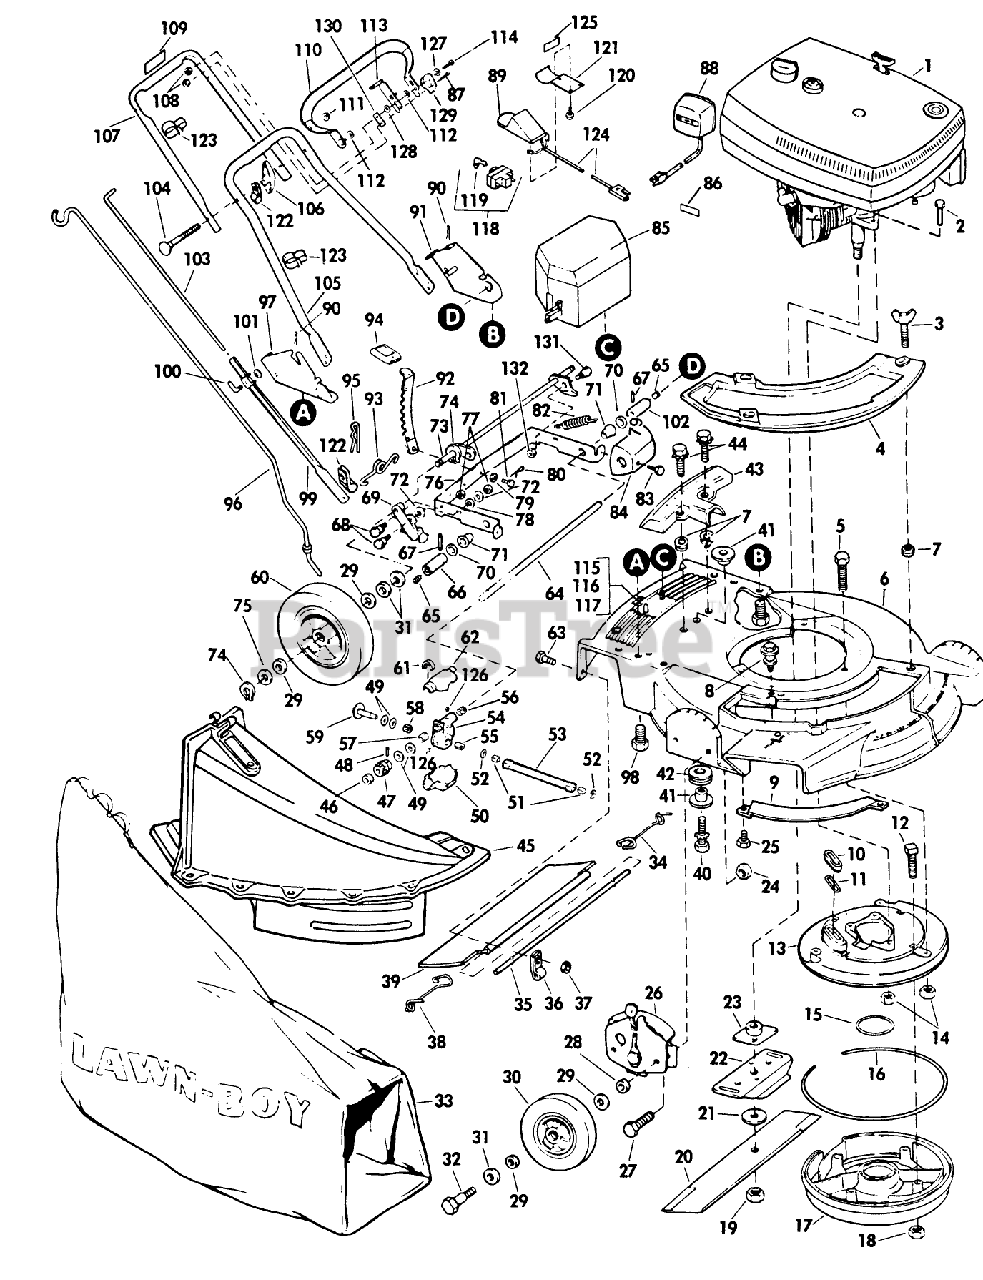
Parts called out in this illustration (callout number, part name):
1	See Note #2 at bottom of this page.
2	BOLT F
3	WING SCREW LAWRE
5	SCREW V
9	BAR-TOE
10	SLEEVE
11	GASKET S
12	SCREW
14	NUT-LOCK F
16	Gasket Muffler (outside)
18	LOCKNUT E
19	NUT-BLADE
21	WASHER
23	PLATE AND COLLAR ASM
24	NUT-LOCK F
28	WASHER WROUGHT
29	WASHER
30	WHEEL & TIRE KIT
31	SPACER
32	BOLT WHEEL
33	ORD LB 89802 WHOLE GOODS
34	SPRIG T/SHLD ASOC
35	ROD 21" ADVANCE
36	CLAMP ROD KMC
37	LOCKNUT E
38	SPRING;TRAILING SHIELD RH
41	SPACER ECK PRES
42	GROMMET
43	COVER
44	SCREW SEMS TRM HEX HD
46	WASHER
48	ROLL PIN
49	THRUST WASHER
51	BUSHING
52	O Ring
58	NEEDLE BEARING
62	GEAR COVER UPPER
64	DRIVE SHFT TAG AY
65	Plug
67	PIN
68	BOLT RB&W
72	WASHER S
74	RET RING
75	SPACER
77	STOP NUT
79	WASHER SPRING LAR
81	PIN
82	SPRING
84	GUARD
87	SCREW-HANDLE STOP
90	HAIR PIN
92	LEVER
93	SPRING N.A.S
94	KNOB
96	ROD GRASSBAG
98	SCREW
103	ROD CONTROL
106	NUT-WING
107	HANDLE
108	LOCKNUT E
112	WASHER M
113	LEVER LOCKOUT
114	BOLT PIONEER
126	**FITTING LINCOLN
128	WASHER
130	HANDLE STOP
131	BOLT RB&W
132	LOCKNUT E
